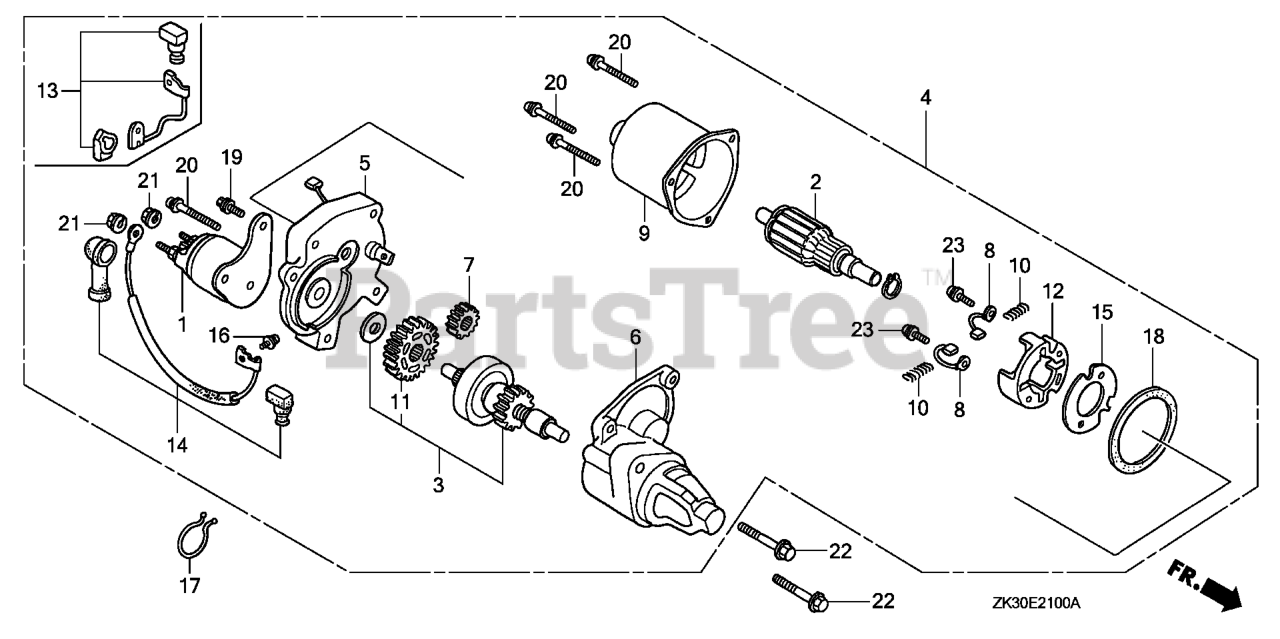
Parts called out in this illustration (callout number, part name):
1	CONTACTOR ASSY.
2	ARMATURE
3	CLUTCH, OVERRUNNING
4	STARTER MOTOR UNIT
5	BRACKET, CENTER
6	BRACKET, FR.
7	GEAR, DRIVE PINION
8	BRUSH
9	YOKE
10	SPRING, BRUSH RETURN
11	GEAR, REDUCTION
12	HOLDER, BRUSH
14	WIRE, WATER COVER
15	INSULATOR
16	SCREW-WASHER (4X6)
18	GASKET
19	BOLT-WASHER (5X14)
19	SCREW-WASHER (5X14)
20	SCREW-WASHER (5X3)
21	NUT-WASHER (6MM)
22	BOLT, FLANGE (8X35)
